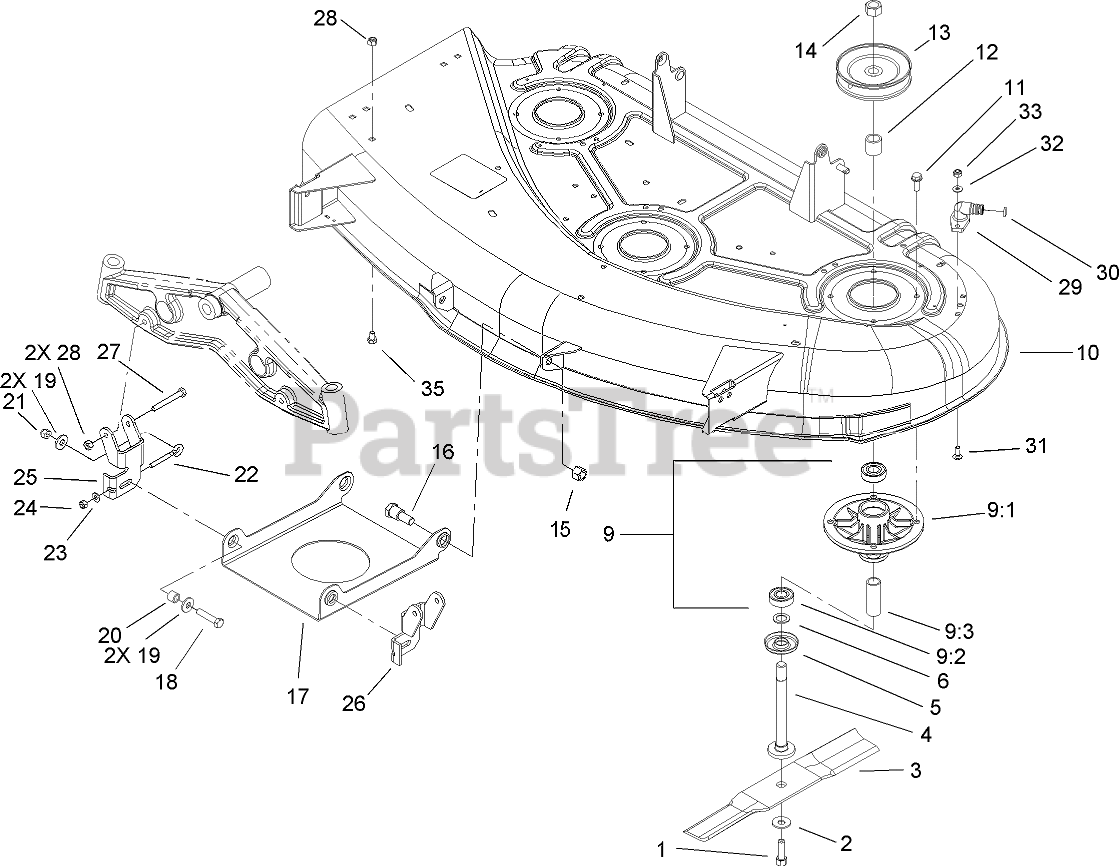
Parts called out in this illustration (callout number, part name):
1	SCREW-HH
2	WASHER-BELLEVILLE
4	SHAFT-SPINDLE
5	SHIELD-BEARING
6	SPACER
9	Spindle ASM
9:1	HOUSING-SPINDLE
9:2	BEARING-BALL
9:3	SPACER
10	DECK ASM
11	SCREW-TAPTITE
12	SPACER
13	PULLEY
14	NUT-HEX
15	NUT-LOCK, NI
16	BOLT-SHOULDER, HH
17	PAN-DECK SUSPENSION, FRONT
18	SCREW-HH
19	WASHER-HARDENED
20	SPACER
21	NUT-LOCK, NI
22	SCREW-ADJUSTING
23	WASHER-FLAT
24	NUT-LOCK, NI
25	BRACKET-RH
26	BRACKET-LH
27	SCREW-HH
28	NUT-LOCK, NI
29	FITTING-WASHOUT
30	O-RING
31	BOLT-CARR
32	WASHER-FLAT
33	NUT-LOCK, NI
35	SCREW-HH
